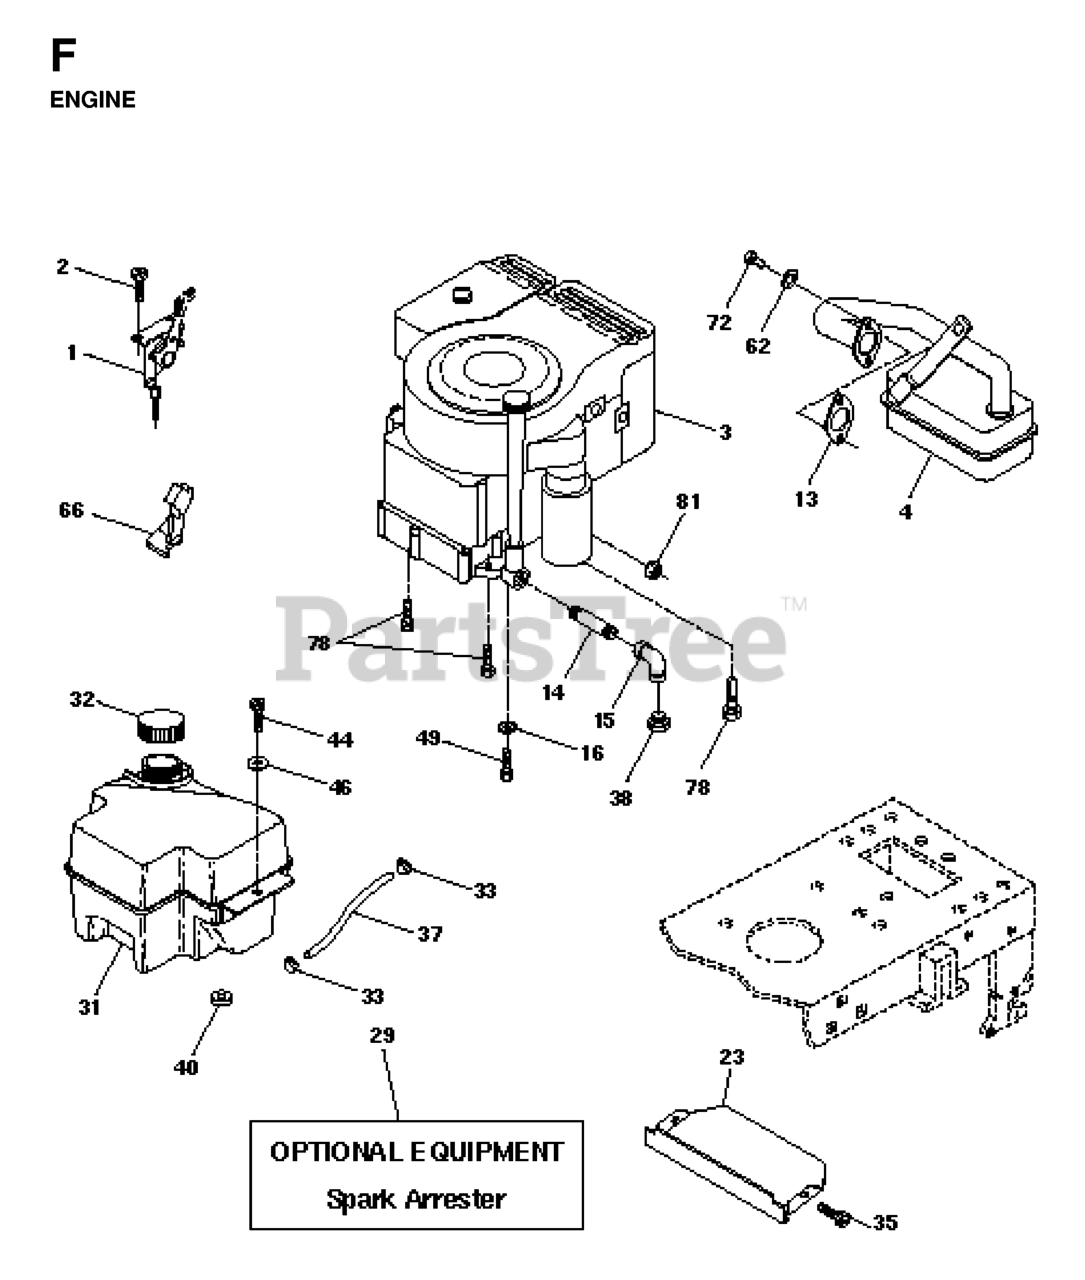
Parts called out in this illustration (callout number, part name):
1	CONTROL
2	SCREW LT
4	MUFFLER.LT.BRIGGS.14HP.IC/OHV
13	GASKET.ENG.1.313 ID.TIN PLATED
14	Nipple Pipe 3/8 Npt X 3-1/2
15	ELBOW
16	LOCKWASHER
29	KIT.SPARK ARRESTOR 794945 B&S
31	FUEL TANK
32	FUEL CAP
33	HOSE CLAMP
35	SCREW.THDROL.5/16-18X3/4.TTY
37	LINE.FUEL.20
40	BUSHING.SNAP.NYL.BLK.
44	SCREW HEX CRT
49	SCREW GTV
62	WASHER.LOCK.HVY.HLCL.SPR.5/16
66	STOP THROTTLE
72	SCREW
78	SCREW
81	NUT FLANGE 1/4-20 STARTER NUT
